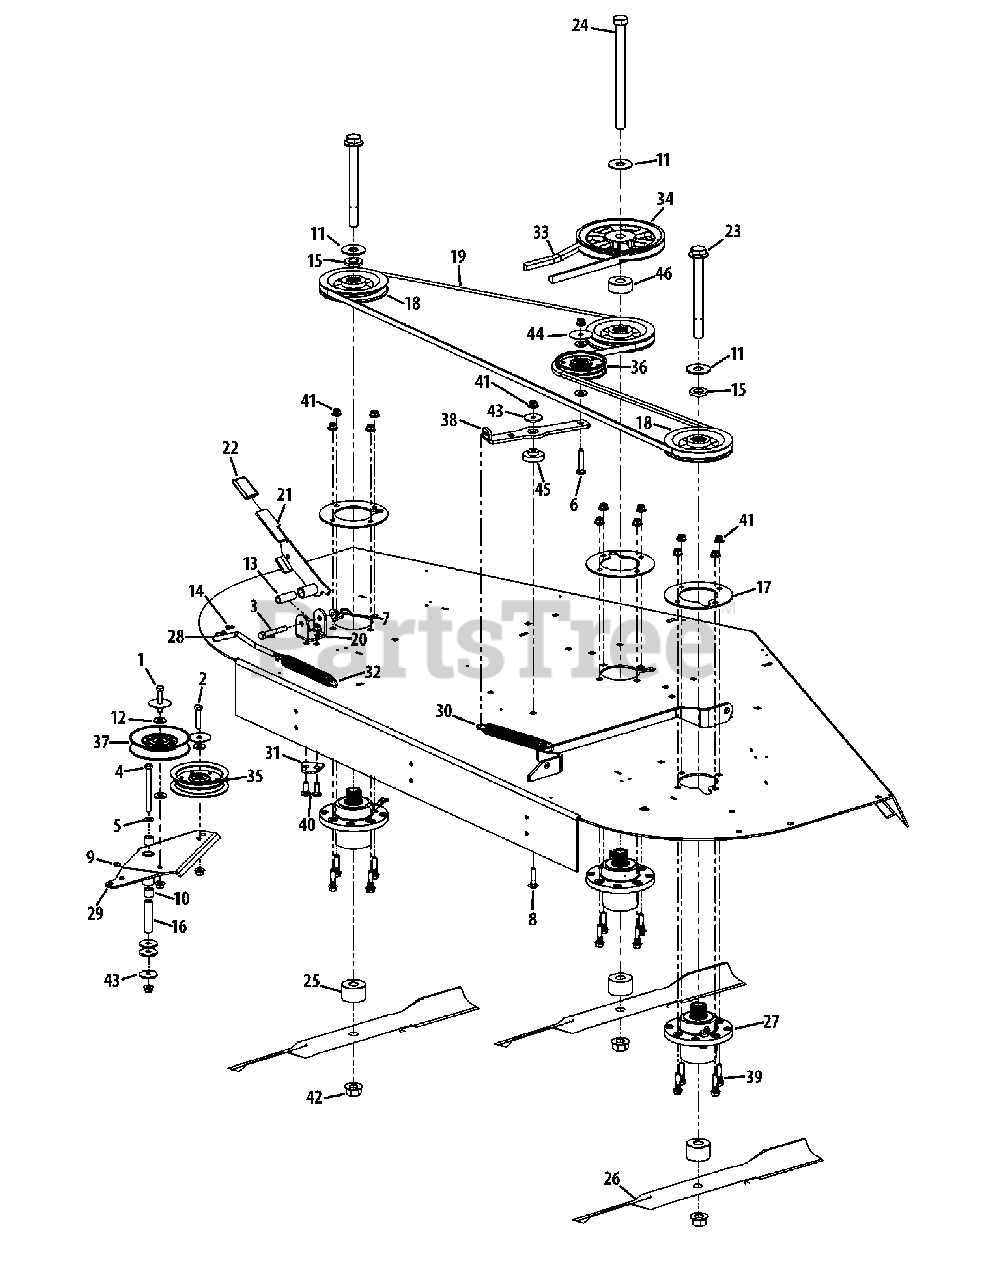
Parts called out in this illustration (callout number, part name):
1	Hex Screw, 3/8-16 x 2.00
2	Hex Screw, 3/8-16 x 1.75
3	Hex Screw, 3/8-16 x 2.50
4	Hex Screw, 3/8-16 x 4.00
5	Washer, .406 x .813 x .063
6	Carriage Bolt, 3/8-16 x 2.00
7	Flange Counter Lock Nut, 3/8-16
8	Carriage Bolt. 3/8-16 x 1.50
9	Grease Fitting, 1/4-28
10	Sleeve Bearing, .628 x.753 x.625
11	Washer, .781 x 2.00 x .105
12	Washer, .406 x 1.00 x .105
13	Spacer, .390 x .630 x 1.75
14	Internal Cotter Pin, .072 x 1.12
15	Spacer, .812 x 1.47 x .218
16	Spacer, .390 x .635 x 2.75
17	Spindle Support Plate
19	V-Belt
20	Idler Tension Bracket
21	Tension Handle Weldment
22	Idler Tension Handle Grip
23	Hex Screw, 3/4-16 x 7.50
24	Hex Screw, 3/4-16 x 9.50
25	Spacer, .760 x 2.00 x 1.28
26	Blade, 25"
26	Bahia Blade (Low Lift)
27	Spindle Assembly
28	Idler Control Rod
29	Idler Double Weldment
30	Extension Spring, .94 x 7.57 x .14
31	Idler Spring Bracket Adapter Plate
32	Extension Spring, .94 x 7.74 x .14
35	Idler Pulley
36	Idler Pulley
37	Idler Pulley
38	Deck Idler Arm
39	Flange Bolt, 3/8-16 x 1.5
40	Carriage Bolt, 3/8-16 x 1.00
41	Flange Lock Nut, 3/8-16
42	Flange Lock Nut, 3/4-16
43	Flat Washer, .390 x 1.500 x .134
44	Flat Washer, .406 x 1.92 x .060
45	Shoulder Spacer, .854 x .280
46	Spacer, .760 x 2.00 x .925
